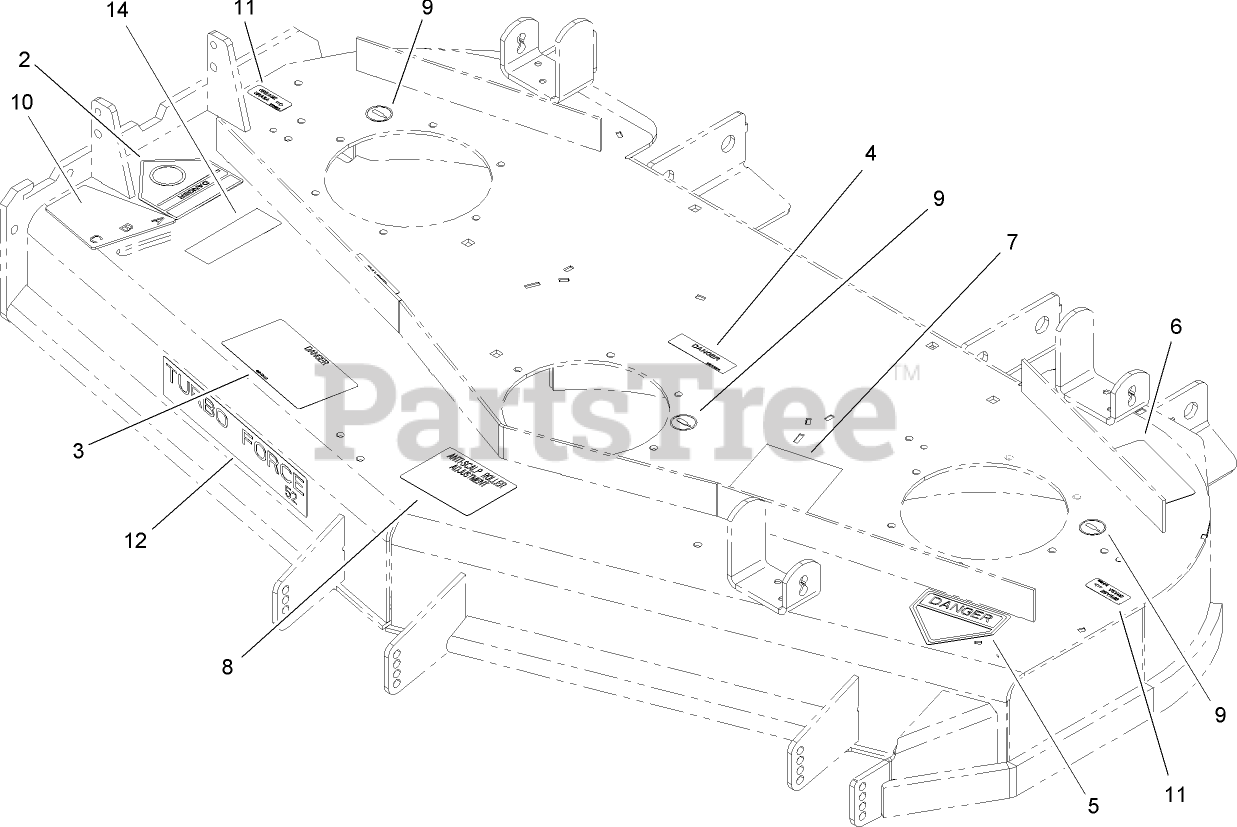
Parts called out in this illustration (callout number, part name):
2	DECAL-DANGER
3	DECAL-DANGER, THROWN OBJECT
4	DECAL-COVER, MISSING
5	DECAL-DANGER
6	DECAL-TORQUE
7	DECAL-AID, SERVICE
8	DECAL-SCALP, ANTI
9	DECAL-GREASE
10	DECAL-ADJUSTMENT, BAFFLE
11	Decal-Grease
14	DECAL-WARNING
